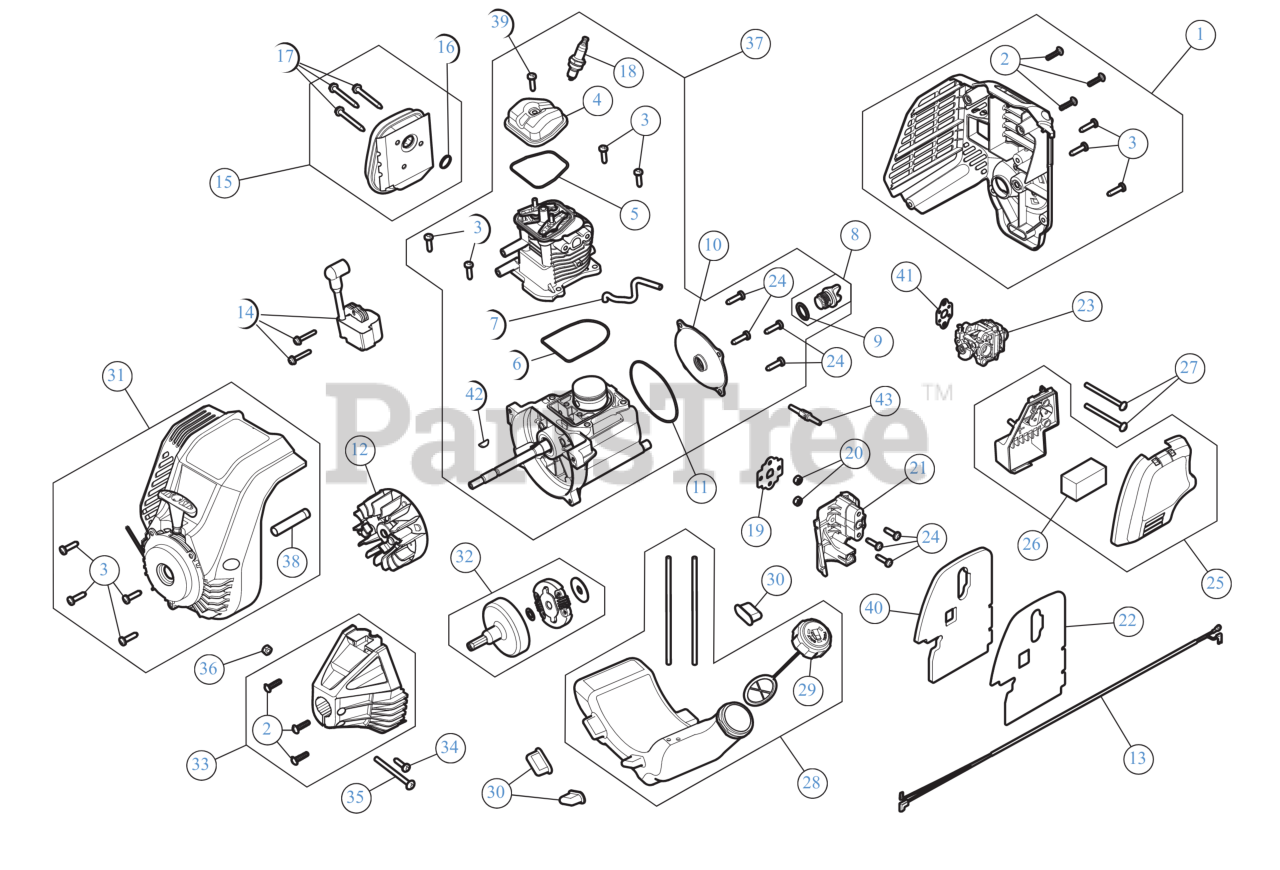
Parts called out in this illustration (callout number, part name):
1	REAR ENGINE COVER
2	SCREW 8-16 x 3/4
3	SCREW M5-0.8 x 19
4	ROCKER COVER
6	O-RING CYL AC5
7	BREATHER HOSE
8	OIL PLUG
9	RING, OIL PLUG (AC
10	CRANKCASE COVER
11	O-RING CRNKCSE CVR
12	FLYWHEEL ASSEMBLY AC3.1
13	LEAD WIRES
14	MODULE ASSEMBLY
15	MUFFLER ASSEMBLY
16	GASKET/MUFFLER
17	SCREW M5 x 44MM
18	SPARK PLUG 4 CYCL
19	GASKET/INSULATOR
21	CARB INSULATOR
23	CARBURETOR
24	SCREW, M5 X18
25	AIR CLEANER COVER
26	AIR FILTER
27	SCREW 10-32X2.5
28	FUEL TANK ASSEMBLY
29	FUEL CAP ASSEMBLY 43MM-6 W/O HOLE
30	FUEL TANK PADS
31	STARTER HOUSING (MTD RED)
32	CLUTCH ASSEMBLY
33	CLUTCH COVER
34	SCREW, 8-32 x .312 P
37	SHORT BLOCK
38	SPACER :2.165"
39	SCR, VALVE COVER
40	HEAT SHIELD
41	CARBURETOR GASKET
42	WOODRUFF KEY #403-.125 x .375
43	BREATHER HOUSING
